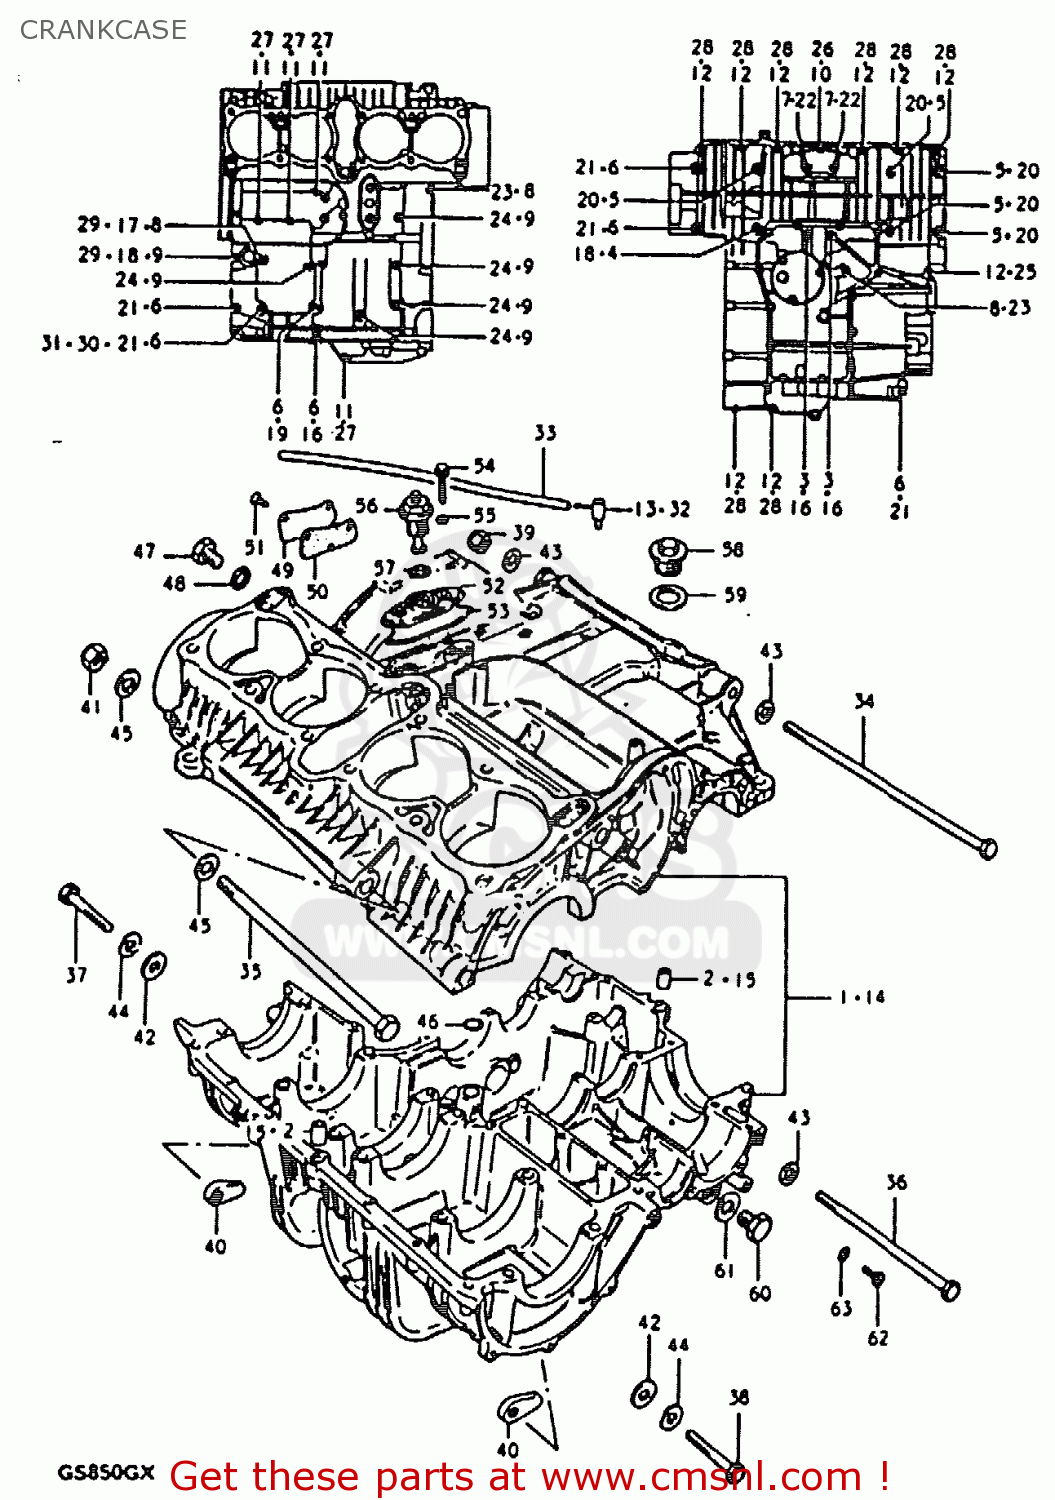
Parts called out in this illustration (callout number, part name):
1	CRANKCASE SET
2	PIN
3	BOLT
4	BOLT
5	BOLT 8X90
6	BOLT 8X65
7	BOLT
8	BOLT (6X90)
9	BOLT (6X75)
10	BOLT ,6X50
11	BOLT,UNDER
12	BOLT 6X35
13	BPLUG,BEVEL GEAR BREATHER
14	CRANKCASE SET
15	PIN
16	BOLT
17	BOLT
18	BOLT
19	BOLT
20	BOLT 8X90
21	BOLT 8X65
22	BOLT
23	BOLT (6X90)
24	BOLT (6X75)
25	BOLT
26	BOLT ,6X50
27	BOLT,UNDER
28	BOLT 6X35
29	NUT
30	NUT
31	GASKET 8.2X14X1 (NAS)
32	BPLUG,BEVEL GEAR BREATHER
33	HOSE
34	BOLT 10X270
35	SHAFT,REAR SWING ARM
36	BOLT(10X165)
37	BOLT 10X60
38	BOLT (10X50)
39	NUT
40	NUT
41	NUT 12MM
42	WASHER(10.5X20X3.2)
43	WASHER
44	LOCK WASHER
45	WASHER
46	O RING(D:3.2,ID:12.9)
47	PLUG (14X12)
48	GASKET(14X19.2X2) (NAS)
49	CAP,OIL GALLERY
50	GASKET,OIL GALLERY (MCA)
51	SCREW
52	HOUSING,OIL PRESSURE SWITCH
53	O RING,PRESSURE SWITCH HOUSING
54	BOLT
55	GASKET (NAS)
56	SWITCH ASSEMBLY
57	O RING(D:1.9,ID:18.8)
58	PLUG
59	GASKET
60	PLUG
61	GASKET(14X19.2X2) (NAS)
62	SCREW(6X10)
63	GASKET (NAS)
